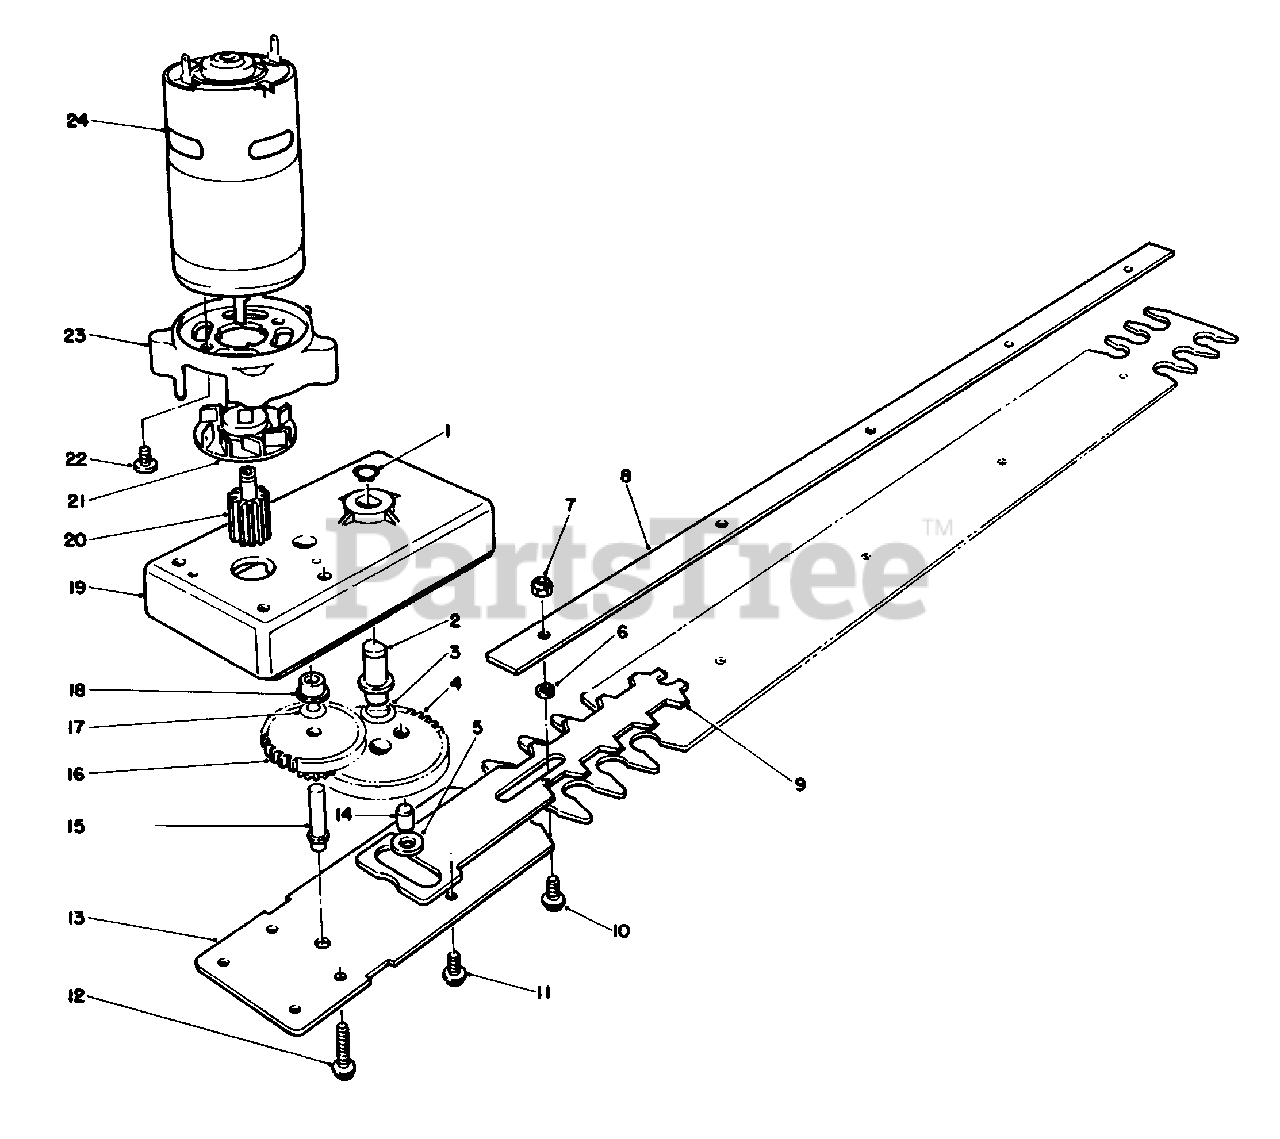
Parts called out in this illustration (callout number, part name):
1	Ring-Retaining
2	Shaft-Driver
3	Washer-Wave
4	Gear-Drive (Incl. Ref. #14)
5	Bushing-Gear, Drive
6	Bushing-Blade
7	Nut-Lock
8	Retainer-Blade
9	Blade-Cutting
10	Screw-Hex Washer Hd.
11	Screw-Hex Washer Hd.
12	Screw-Hex Washer Hd.
13	Blade-Bottom
14	Pin-Drive
15	Shaft-Idler
16	Gear-Idler
17	Washer-Wave
18	Bearing-Idler
19	Housing-Gear Assembly (Incl Ref. 2 & 18)
20	Gear-Motor
21	Fan-Motor
22	Screw-Phil. Pan Hd.
23	Support-Motor
24	Motor Assembly (Incl. Ref. #20-23)
